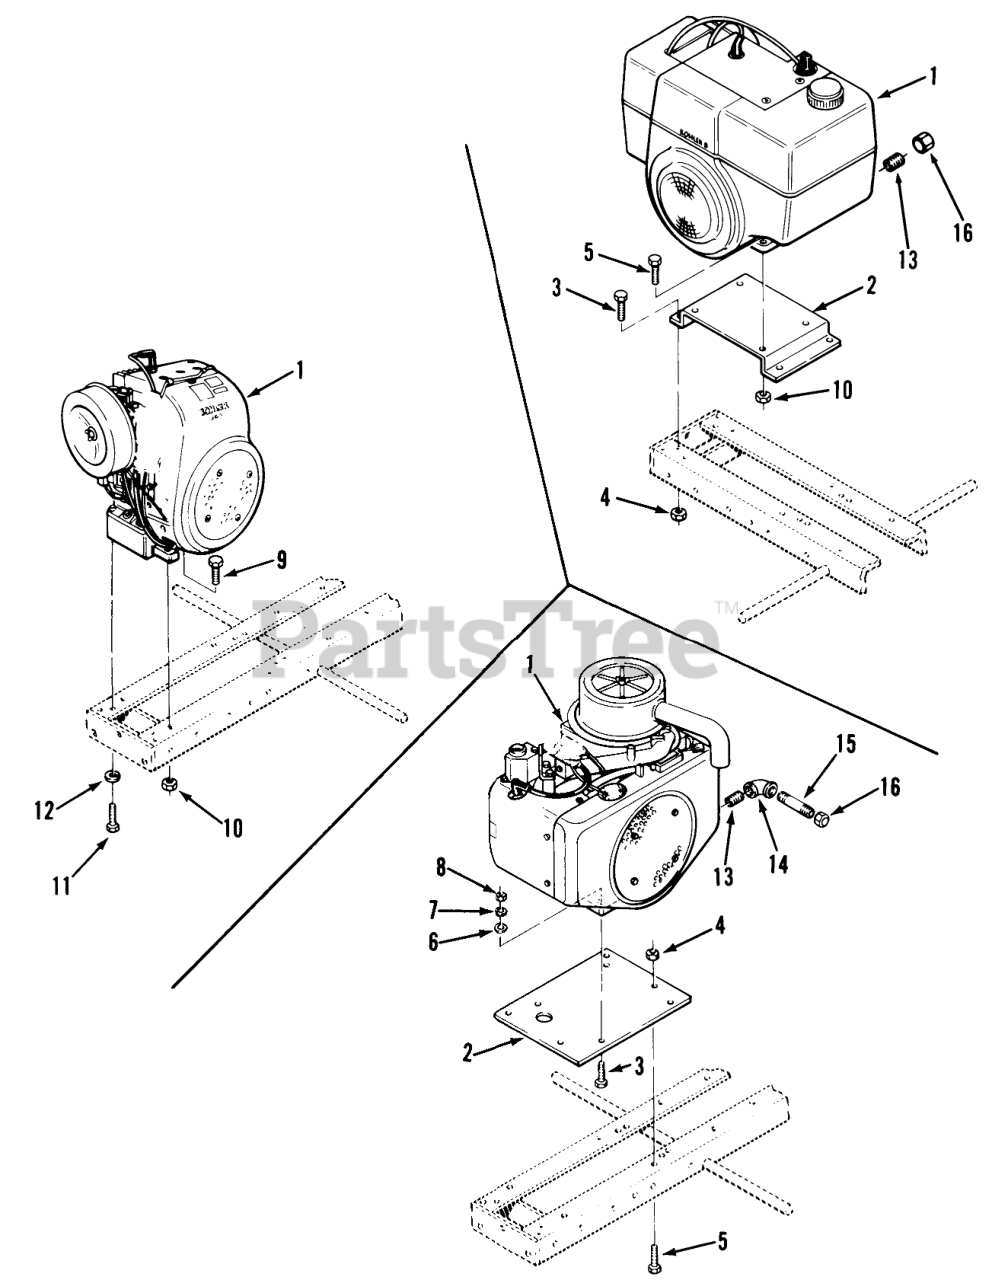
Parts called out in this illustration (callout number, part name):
1	Engine-8HP-Kohler M-8-S Spec PS-301511
1	Engine-1OHP-Kohler M-10-S Spec PS-461521
1	Engine 12HP Kohler M-12-S Spec 471527312
1	Engine-14HP-Kohler M-14-S Spec PS-601524
1	Engine-16HP-Kohler M-16-S Spec PS-711523
1	Engine-18HP-Kohler M-18QS Spec PS-24510 418-8, 418-A
1	Engine-18HP-Kohler M-18QS Spec PS-12536 418-C
2	ENGINE PLATE B
2	Engine Base
3	BOLT
3	Bolt
4	NUT
5	Bolt
6	Washer
7	LOCKWASHER
8	Nut
9	BOLT
10	NUT
11	BOLT
12	LOCKWASHER
13	Nipple 3/8
13	Nipple 1/2"
14	Elbow 3/8
15	Nipple 3/8 x 4 1/2
16	Cap
16	CAP-PIPE 1/2 IN
